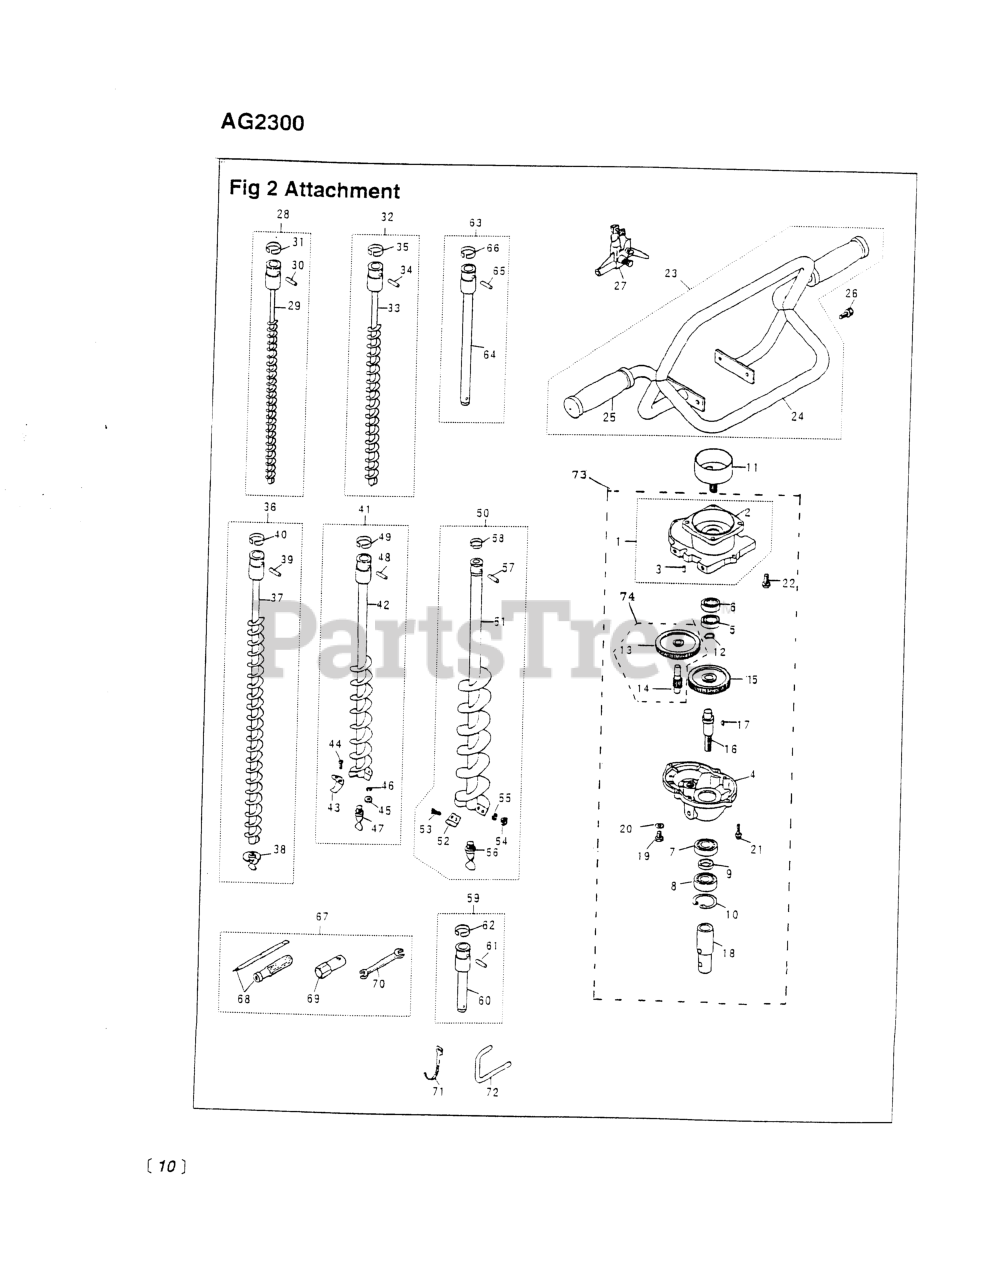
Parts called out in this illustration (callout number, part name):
3	PIN, DOWEL
4	CASE (USE -11201)
5	BEARING
10	RING, SNAP, M35 X 1.5
11	DRUM, CLUTCH
12	RING, SNAP (RPLS 3130-13270)
16	SHAFT, PTO
17	KEY
18	SHAFT
19	BOLT, M6 x 10
20	WASHER, M6 X .8
21	BOLT M5 x 20 (RPLS -12280)
22	BOLT, M6 x 16
24	HANDLE
25	GRIP (USE -14221)
26	BOLT, M6 x 16
27	LEVER, THROTTLE
28	DRILL S20 ASS
29	DRILL S20
30	PIN
31	CLIP
32	DRILL S30 ASS
33	DRILL S30
34	PIN
35	CLIP
36	S40 DRILL ASS
37	DRILL S40
39	PIN
40	CLIP
41	DRILL S60 ASS
42	DRILL S60
44	SCREW, M6 X 20
45	NUT, M6 X 5
46	WASHER, M6 X 15
47	BIT
48	PIN
49	CLIP
50	S90 DRILL ASS
51	DRILL S90
52	CHIP S90
53	SCREW, M6 X 20
54	NUT, M6 X 5
55	WASHER, M6 X 15
56	BIT
57	PIN
58	CLIP
59	JOINT L100 ASS
60	JOINT L100
61	PIN
62	CLIP
63	JOINT L300 ASS
64	JOINT L300
65	PIN
66	CLIP
67	TOOL SET
68	SCREWDRIVER
69	SOCKET, HEX, 3/4
70	SPANNER, 8 X 10 (RPLS 2540- )
71	BAND
72	PIN
